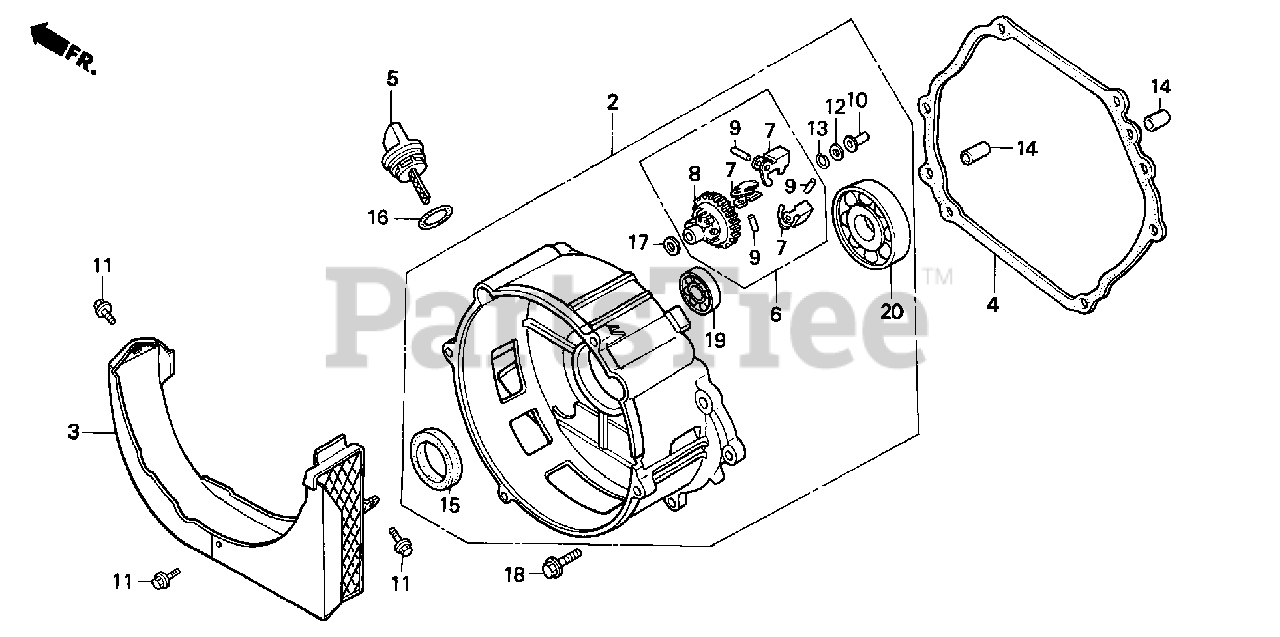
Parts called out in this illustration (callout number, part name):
2	COVER ASSY., CRANKCASE
3	COVER, DUCT
4	GASKET, CASE COVER
5	CAP, OIL FILLER
6	GOVERNOR ASSY.
7	WEIGHT, GOVERNOR
8	HOLDER, GOVERNOR WEIGHT
9	PIN, GOVERNOR WEIGHT
10	SLIDER, GOVERNOR
11	BOLT, FLANGE (5X10)
13	CLIP, GOVERNOR HOLDER
14	PIN, DOWEL (8X12)
15	OIL SEAL (35X52X8)
16	O-RING (26X2.7)
17	WASHER, PLAIN (6MM)
18	BOLT, FLANGE (8X40)
19	BEARING, RADIAL BALL (6202)
20	BEARING, RADIAL BALL (6207)
